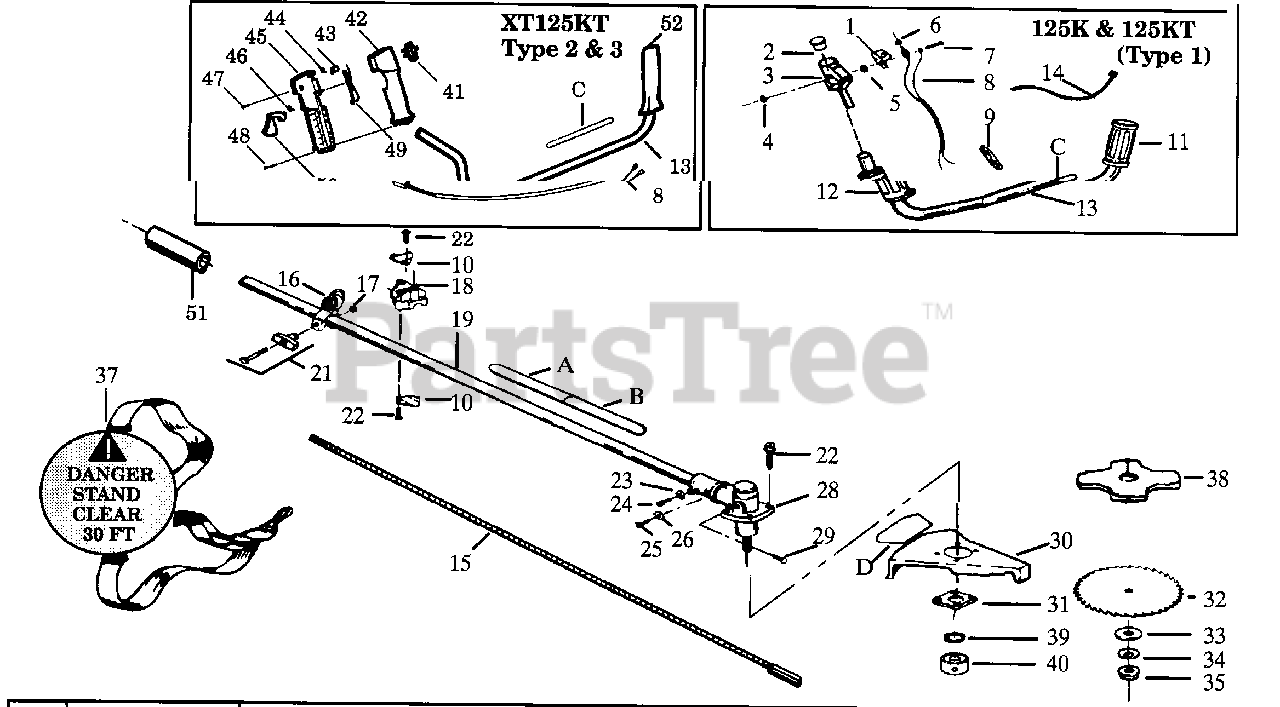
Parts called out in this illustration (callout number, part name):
1	Switch Bracket Type 1 Model XT125K,XT125KT
2	Handlebar Cap Type 1 Model XT125K,XT125KT
3	Throttle Lever Ass'y. w/Lock Type 1 Model XT125K,XT125KT
4	Nut Type 1 Model XT125K,XT125KT
5	Spacer Type 1 Model XT125K,XT125KT
6	Nut Type 1 Model XT125K,XT125KT
7	Screw Type 1 Model XT125K,XT125KT
8	Type 1 Model XT125K,XT125KT
8	Types 2 & 3 Model XT125KT
9	Terminal Lock Type 1 Model XT125K,XT125KT
10	Handlebar Bracket
11	Handlebar Grip-Left Type 1 Model XT125K, XT125KT
12	Handlebar Grip-Right Type 1 Model XT125K, XT125KT
13	Type 1 Model XT125K,XT125KT
13	Types 2 & 3 Model XT125KT
14	Tie Strap Type 1 Model XT125K,XT125KT
15	Drive Shaft
16	Clamp Harness Ass'y.
18	Handlebar Clamp
19	Drive Shaft Housing
21	"T" Handle Ass'y.
23	Lockwasher
26	Lockwasher
28	Gear Box Ass'y.
30	Shield
31	Shield Retention Plate
32	Brush Blade
34	Washer
37	Shoulder Strap
38	4 Point Blade (Optional)
40	Dust Cup
41	Rocker Switch Types 2 & 3 Model XT125KT
42	Throttle Housing Left Types 2 & 3 Model XT125K
43	Throttle Lock Types 2 & 3 Model XT125KT
44	Throttle Spring Types 2 & 3 Model XT125KT
45	Throttle Housing Right Types 2 & 3 Model XT125
46	Trigger Spring Types 2 & 3 Model XT125KT
47	Screw Types 2 & 3 Model XT125KT
48	Screw Types 2 & 3 Model XT125KT
49	Throttle Lockout Types 2 & 3 Model XT125KT
50	Trigger Types 2 & 3 Model XT125KT
51	Pad-Drive Shaft Housing
52	Grip-Handlebar
53	Brush Blade Kit
A	Decal-Shaft Warning (Upper)
B	Decal-Shaft Warning (Lower)
